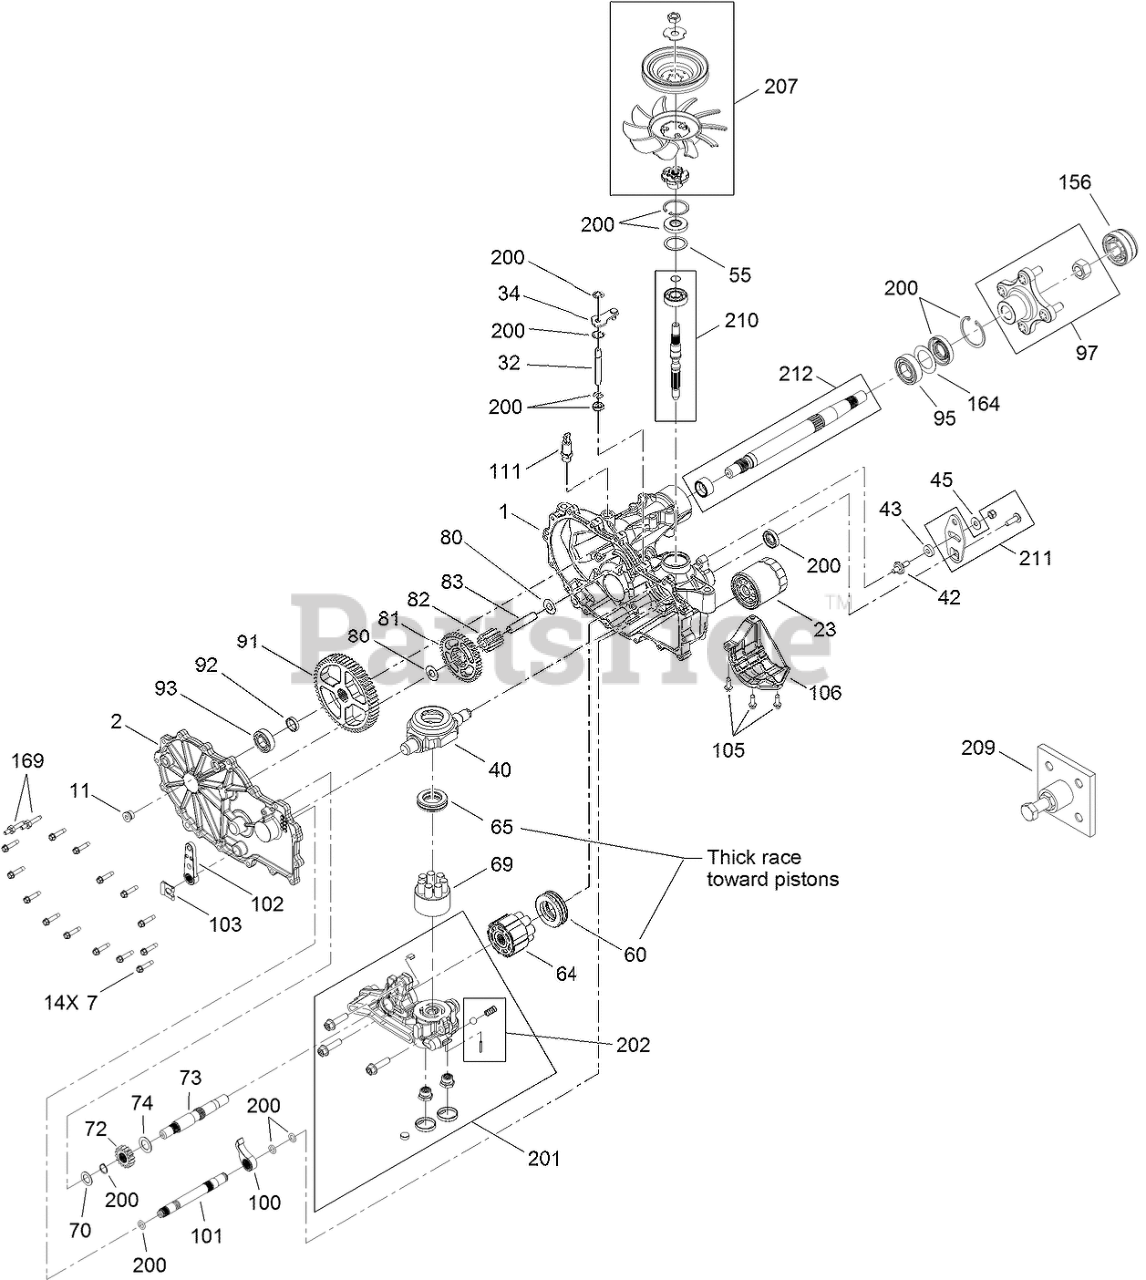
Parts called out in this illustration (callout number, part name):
1	MAIN HOUSING KIT
2	LH SIDE COVER KIT
7	SCREW-HHF
11	PLUG-THREAD, STRAIGHT
23	ELEMENT-OIL FILTER, HYD
32	ROD-BYPASS
34	ARM-BYPASS
40	SWASHPLATE-TRUNNION
43	PUCK-FRICTION
45	WASHER
55	SPACER
60	BEARING-THRUST
64	MOTOR CYLINDER BLOCK KIT
65	BEARING-THRUST
69	PUMP BLOCK ASM
70	WASHER-FLAT
72	GEAR-16T
73	SHAFT-MOTOR
74	WASHER
80	WASHER
81	GEAR-43T
82	GEAR-11T
83	PIN-JACKSHAFT
91	GEAR-54T
92	SPACER
93	BEARING-BALL
95	BEARING-BALL
97	HUB KIT
100	PAWL-BRAKE
101	SHAFT-BRAKE, INBOARD
102	HANDLE-BRAKE
103	CLIP-RETAINING
106	GUARD-FILTER, LH
111	ADAPTER-STRAIGHT
156	COVER-NUT, AXLE
164	SPACER
200	SEAL KIT
201	CENTER SECTION KIT
202	CHARGE RELIEF KIT
207	FAN PULLEY KIT
209	PULLER-HUB, 4 BOLT
210	INPUT SHAFT KIT
211	CONTROL ARM KIT
212	AXLE SHAFT KIT
